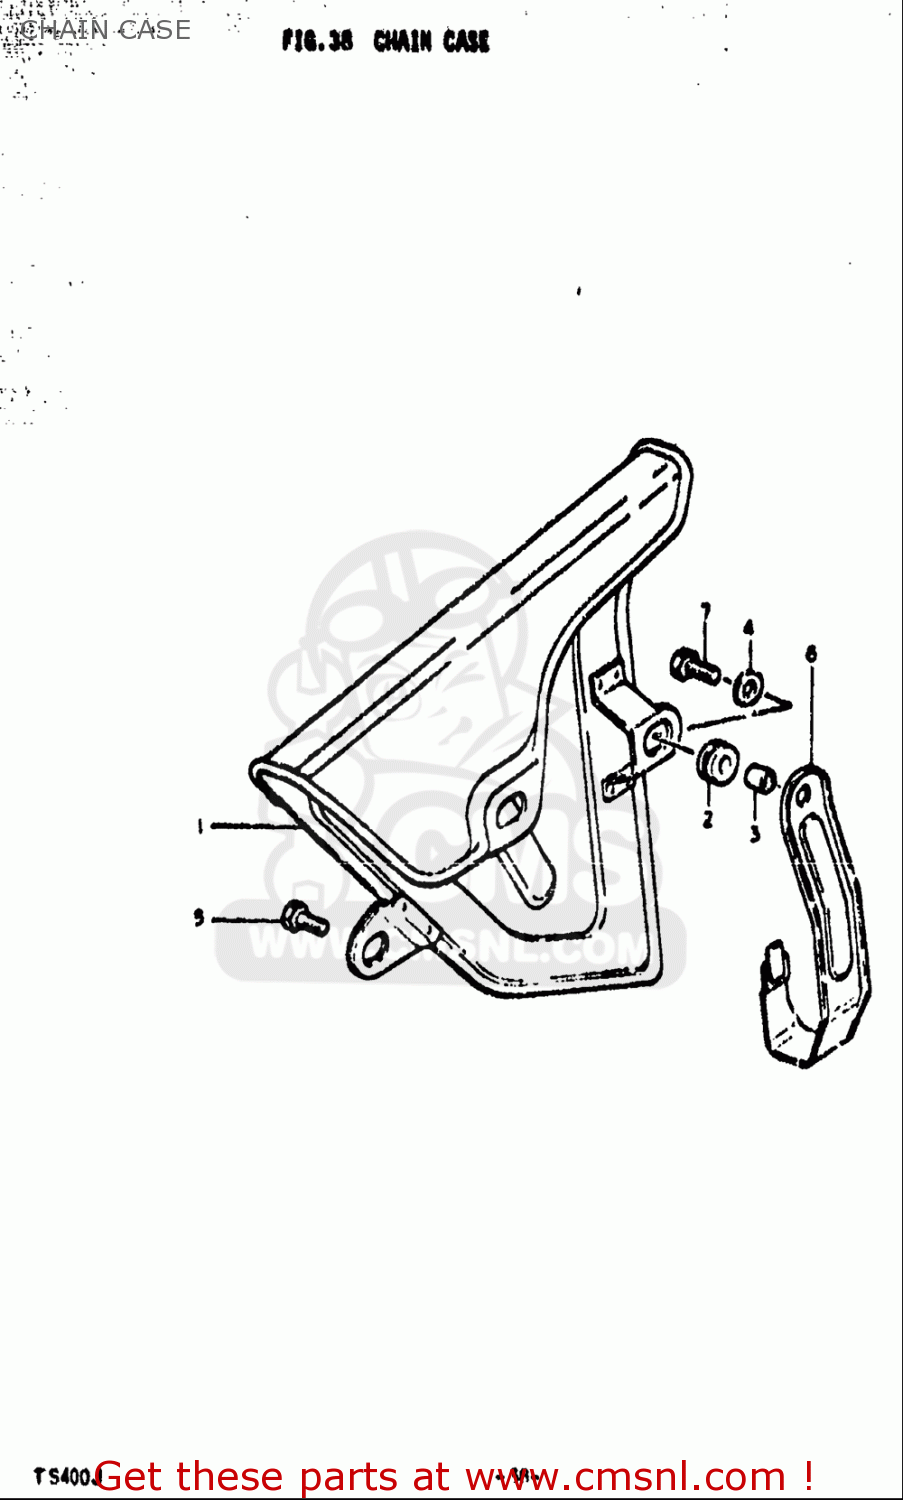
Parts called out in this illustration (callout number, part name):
2	CUSHION
4	WASHER(6.5X20X1.2)
5	BOLT
7	SCREW(6X14)
